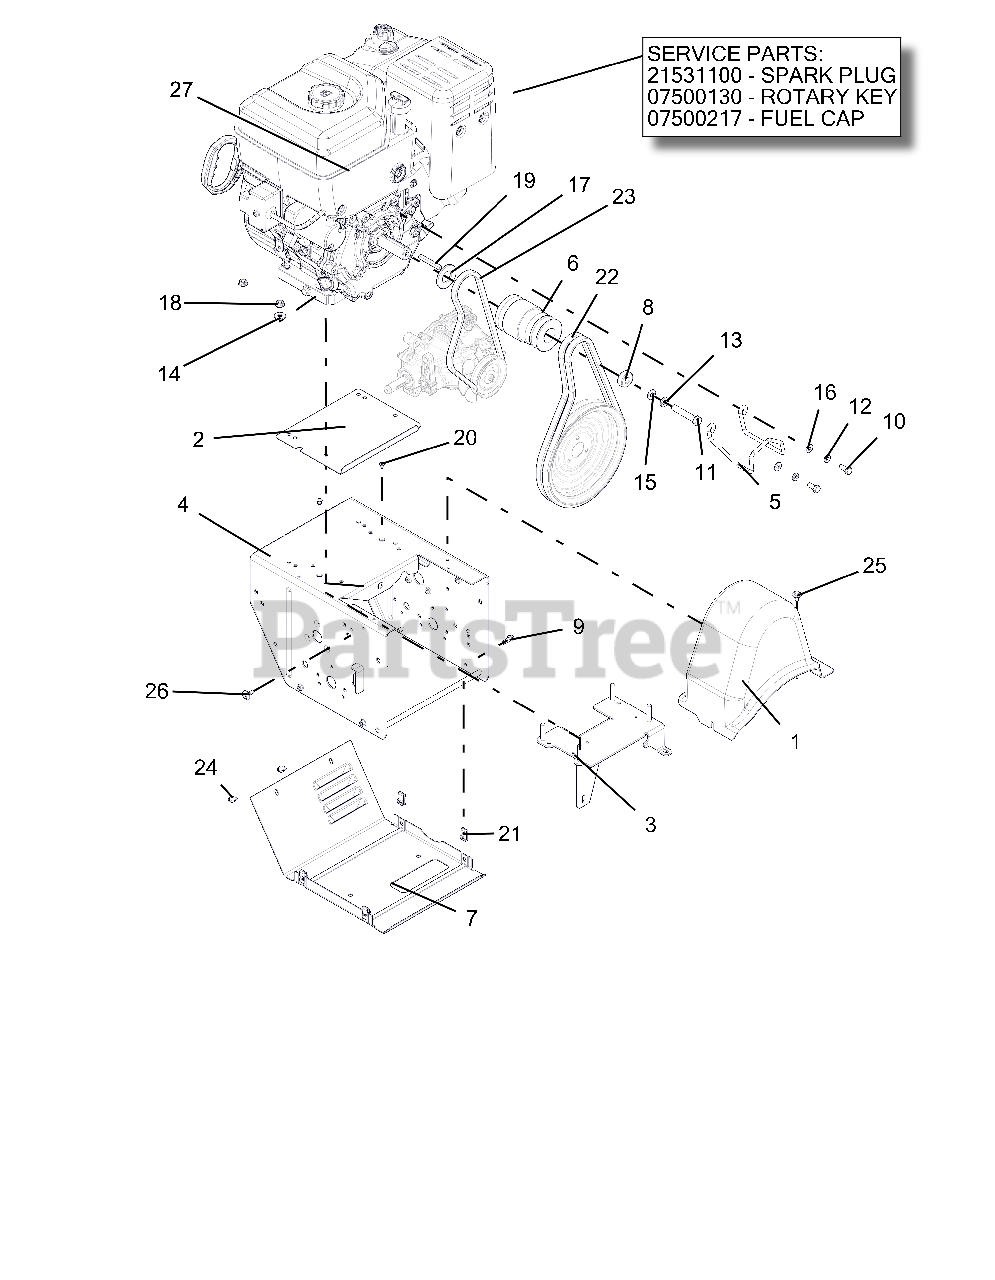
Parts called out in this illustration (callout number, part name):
1	COVER, BELT-LARGE PRO
2	BAFFLE,ENGINE-PRO SERIES
3	BRACKET, HYDROSTATIC TRANS XLG
4	PRO HYDRO FRAME, MAIN
5	FINGER, BELT
6	SHEAVE, COMBO HYDRO TRACK 4L
7	COVER, BOTTOM - VENTILATED
8	BSHG-SPACER .47X1.25X.50
9	BLT-HEX .25-20X.75 HWH YZ GR5
10	BLT-HEX .31-24X.75 YWZC GR5
11	BLT-HEX .44-20X2.50 GR5 YWZC
12	WSHR-LK .312X.097 HVY YWZC
13	@WSHR-LK .44X.109 REG YWZC
14	@WSHR-FL-STL.38X.875X.083 YWZC
15	@WSHR-FL-STL.406X.812X.065 YWZ
16	@WSHR-FL-STL.344X.688X.065YWZC
17	WSHR-FL-STL- 1.062X2.0X.134 YZ
18	@NUT-LK-CTR-FLG .31-18 YZ GR F
19	KEY .25X.25X2.25
20	RVT-POP .187 YZ
21	NUT-RTNR .25-20X.56
22	V-BELT, HA-RAW EDGE (SET)
23	V-BELT, 4L-WRAPPED
24	SCR-TAP .25-20X.50 HWH TR YWZ
25	SCR-TAP .25-20X.50 LGHWH TR YZ
26	SCR-TAP .25-20X.5 CAPTIVE
27	ENGINE, BRIGGS PF 2100, 240V
27	PLUG, SPARK 20HP B&S VANGUARD
27	KEY, IGNITION ROTARY B&S
27	CAP, FUEL - BRIGGS & STRATTON
